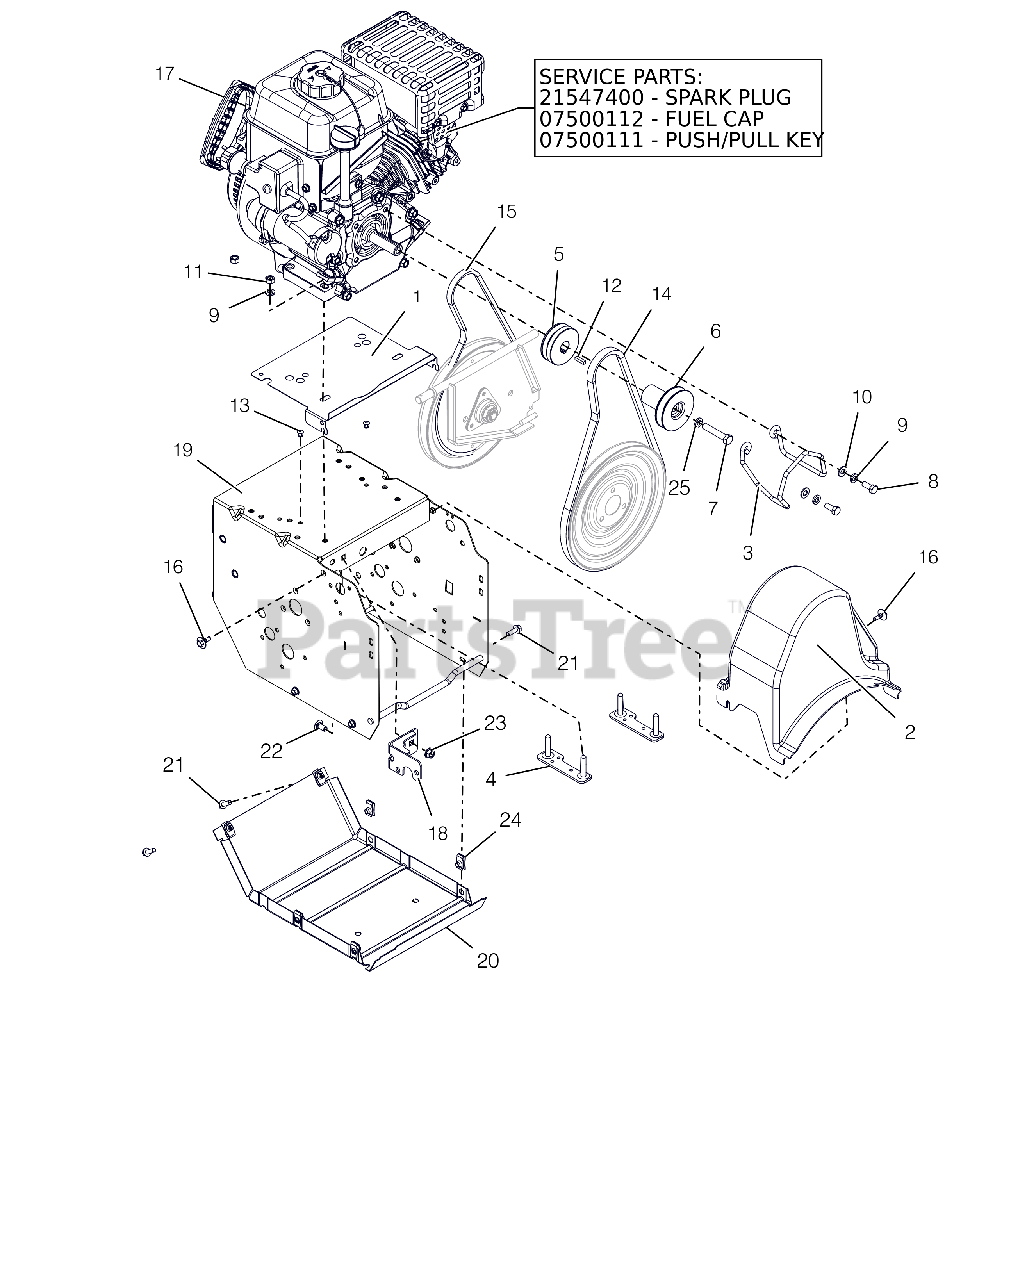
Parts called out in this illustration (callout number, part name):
1	BAFFLE, COMPACT
2	COVER, COMPACT BELT
3	FINGER, BELT
4	STRAP, ENGINE BOLT-WELDMENT
5	SHEAVE, TRACTION-COMPACT TRACK
6	SHEAVE,AUGER 3/4" PM
7	BLT-HEX .38-24X2.0 YWZC
8	BLT-HEX .31-24X.75 YWZC GR5
9	WSHR-LK .312X.097 HVY YWZC
10	@WSHR-FL-STL.344X.688X.065YWZC
11	@NUT-HEX .31-18 YWZC
12	KEY-SQ .188X.75X.188
13	RVT-POP .187 YZ
14	V-BELT, HA-RAW EDGE
15	V-BELT, 3L-WRAPPED
16	SCR-TAP .25-20X.5 CAPTIVE
17	ENGINE, ARIENS AX208 240V/60W
17	PLUG, SPARK
17	CAP, FUEL TANK BLACK
17	KEY, PUSH/PULL LCT (2/PACKAGE)
18	WELDMENT, FRAME BRACKET
19	FRAME, MAIN-WELDMENT
20	COVER, BOTTOM
21	BLT-HEX .25-20X.75 HWH YZ GR5
22	@BLT-RHDSSQNK .31-18X.62 G5YZ
23	@NUT-LK-TOP-FLG .31-18 YWZC
24	NUT-RTNR .25-20X.56
25	WSHR-LK .312X.097 HVY YWZC
